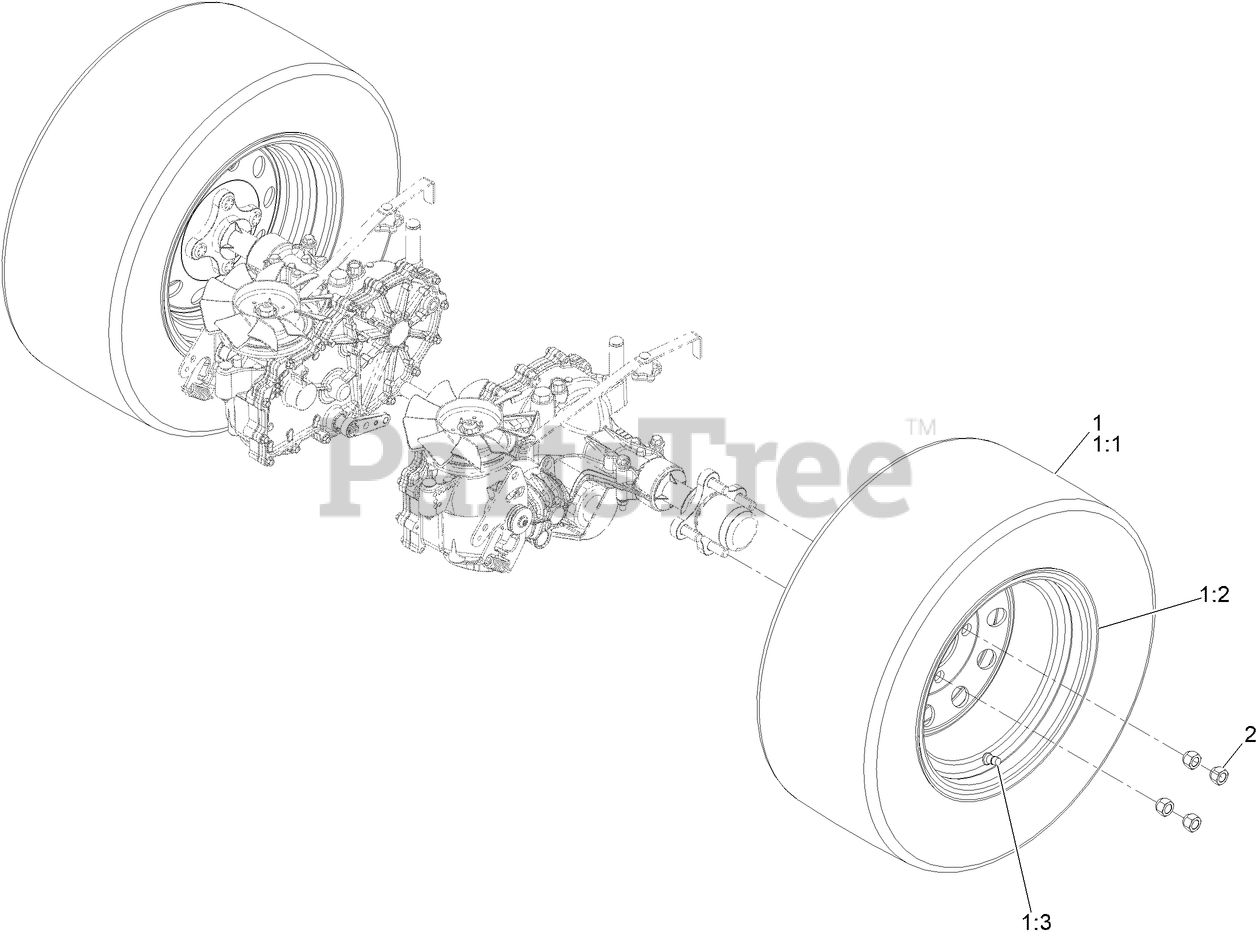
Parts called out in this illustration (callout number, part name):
1	Wheel And Tire ASM
1:3	VALVE
2	NUT-LUG
